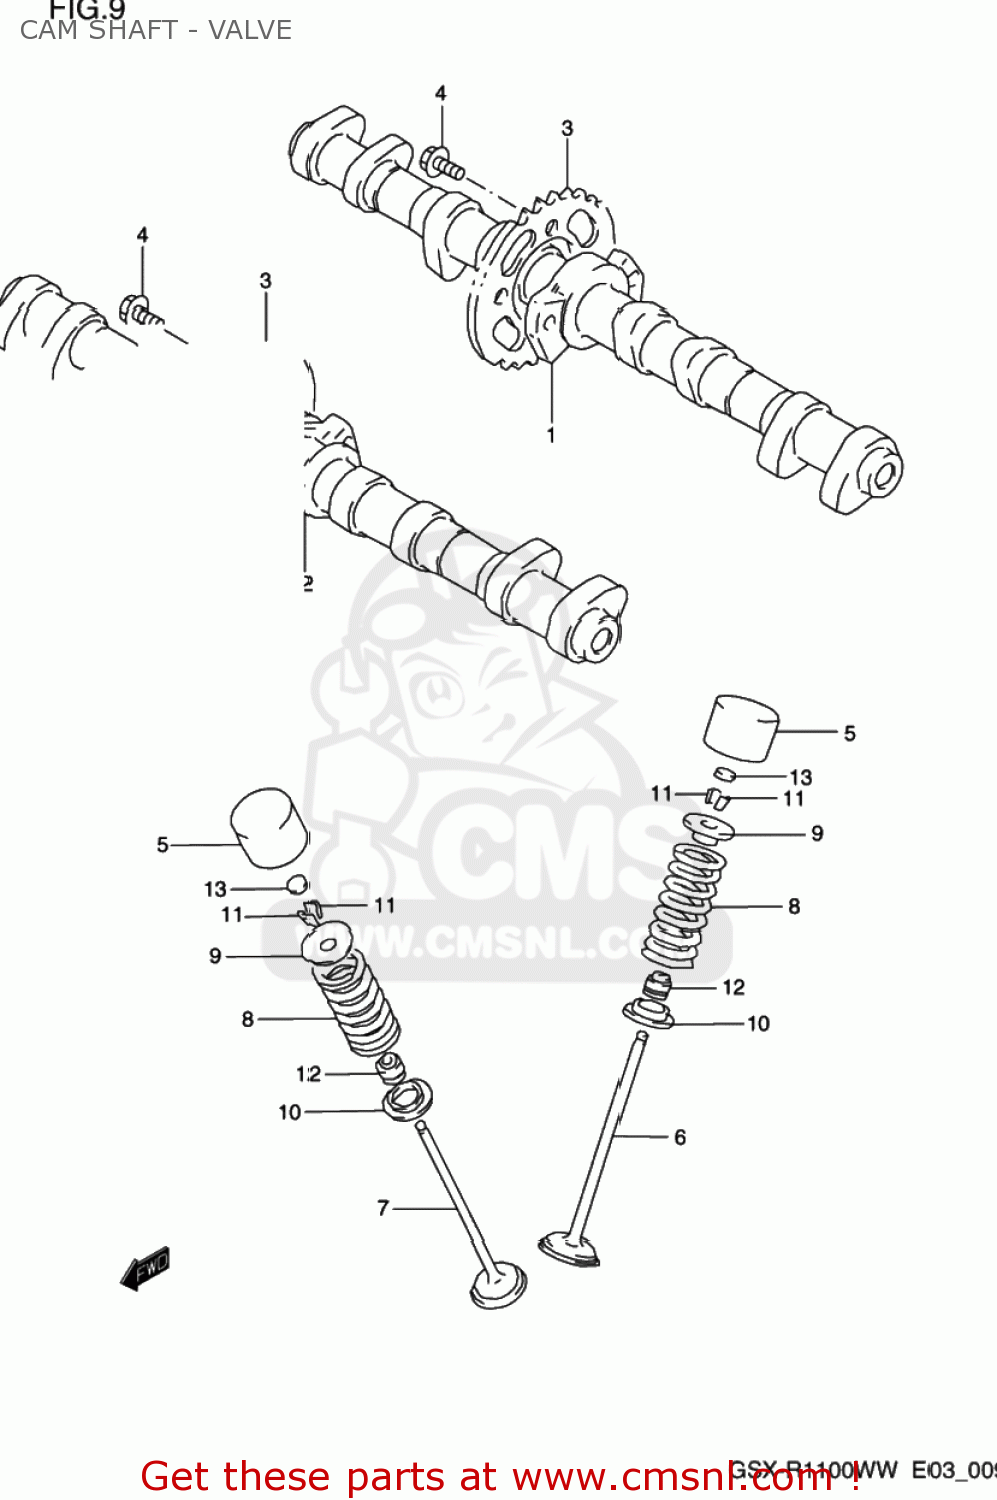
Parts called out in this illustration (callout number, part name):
1	CAMSHAFT,INTAKE
2	CAMSHAFT,EXHAUST
3	SPROCKET,CAMSHAFT
4	BOLT(7X11)
5	TAPPET
6	VALVE,INTAKE
7	VALVE,EXHAUST
8	SPRING,VALVE
9	RETAINER,VALVE SPRING
10	SEAT,VALVE SPRING
11	COTTER VALVE
12	SEAL,OIL(4.5X10X8)
13	SHIM,TAPPET
14	SHIM SET,TAPPET
15	CASE,TAPPET SHIM
